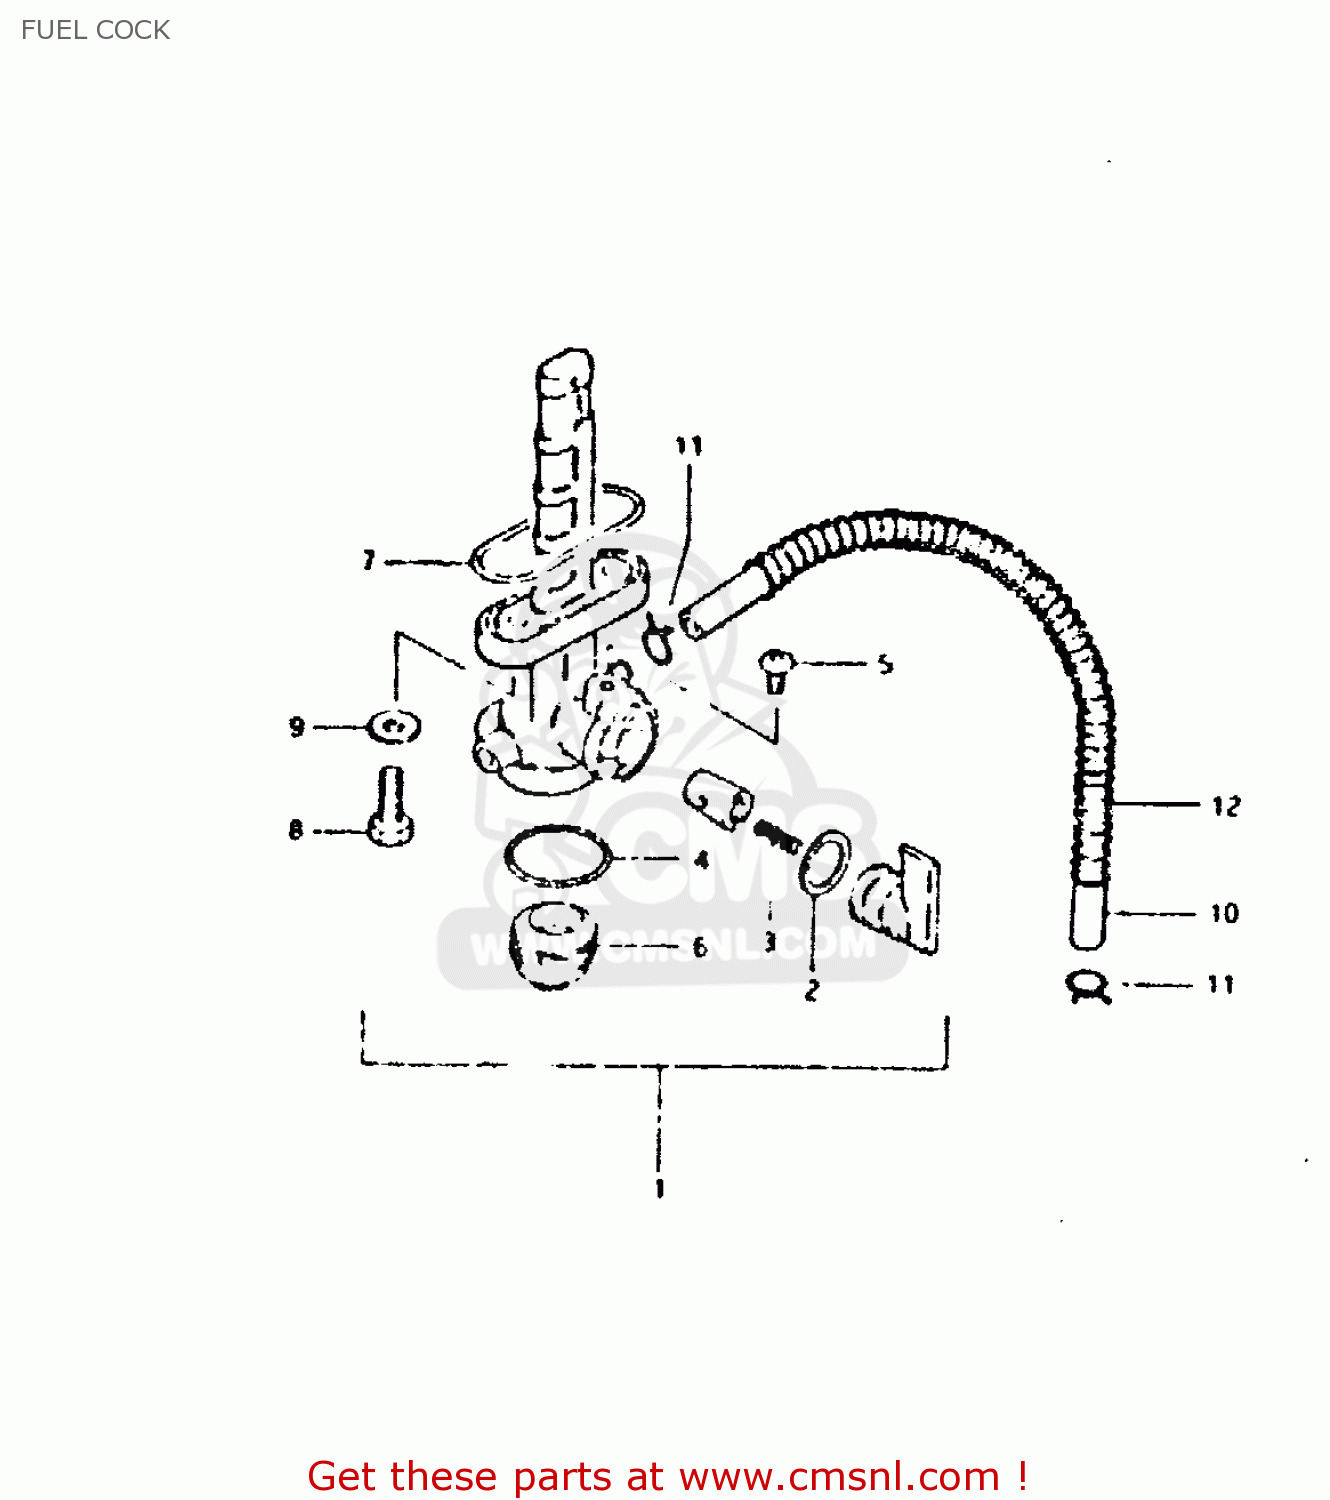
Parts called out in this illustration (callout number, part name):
1	COCK ASSEMBLY,FUEL
2	O-RING
3	SPRING
4	GASKET,FILTER (NAS)
5	SCREW,FUEL COCK LEVER
6	CUP,STRAINER
7	O RING,FUEL COCK
8	BOLT(6X20)
9	GASKET
10	HOSE
11	CLIP
12	SPRING
